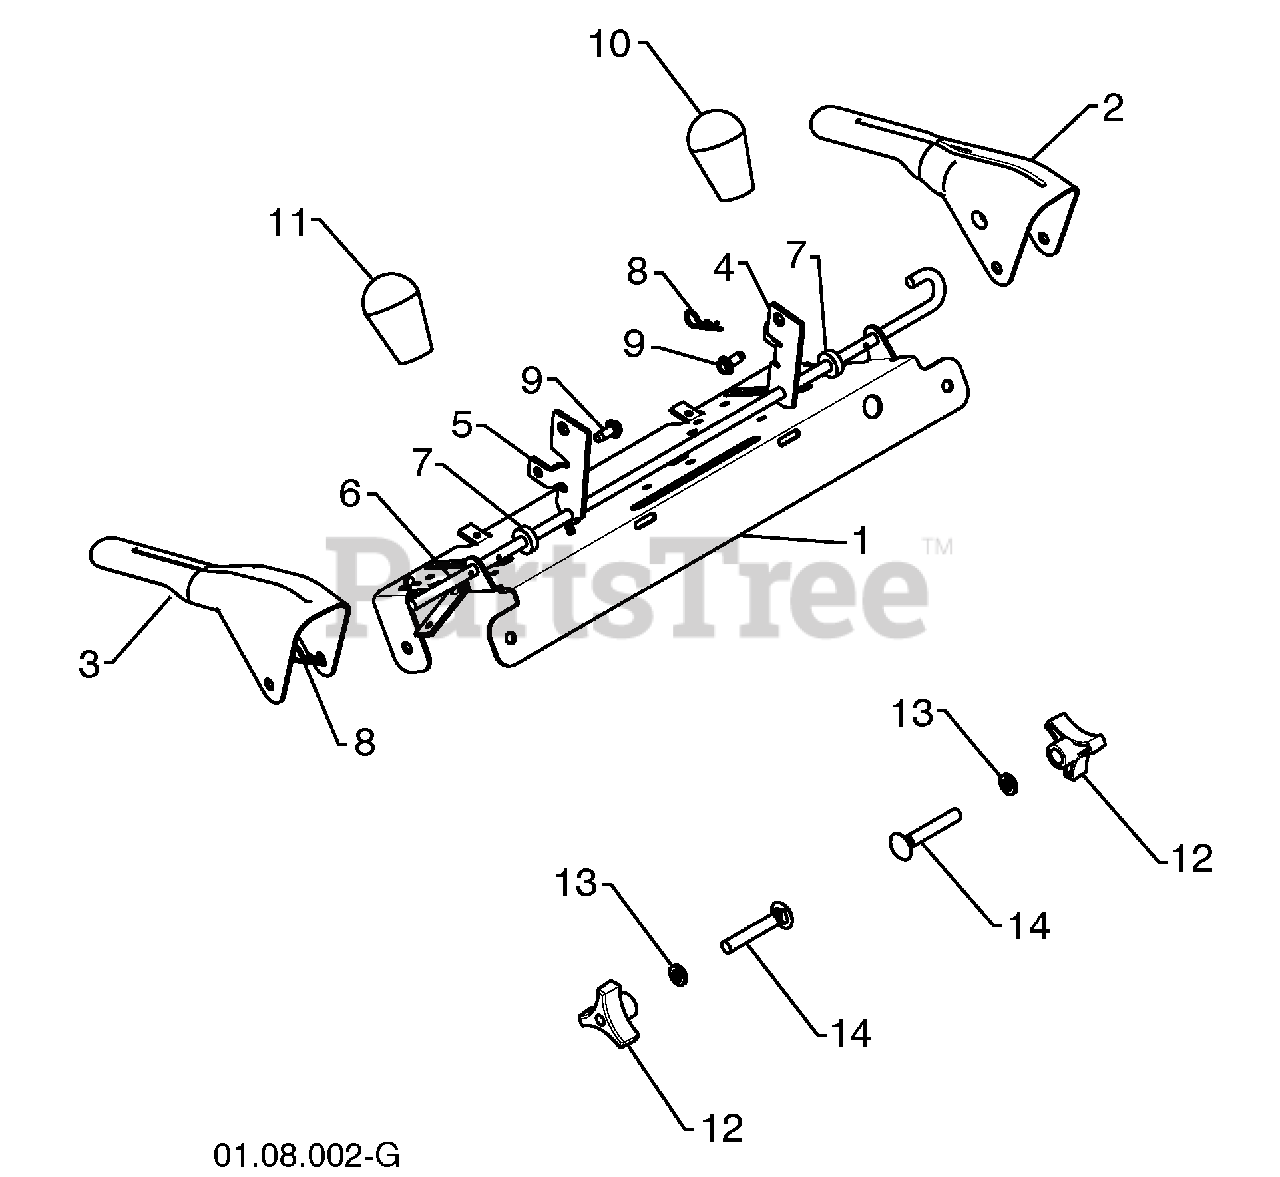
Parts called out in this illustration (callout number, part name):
2	CONTROL LEVER LH
3	CONTROL LEVER RH
4	TRACTION ROD ARM
5	IMPELLER ROD ARM
6	INTERLOCK BAIL
8	RETAINER
9	SCREW 1/4-20 X .62
10	KNOB BLACK
11	KNOB RED
12	HANDLE KNOB
13	WASHER 3/8
14	CARRIAGE BOLT 3/8-16 X 2.25
